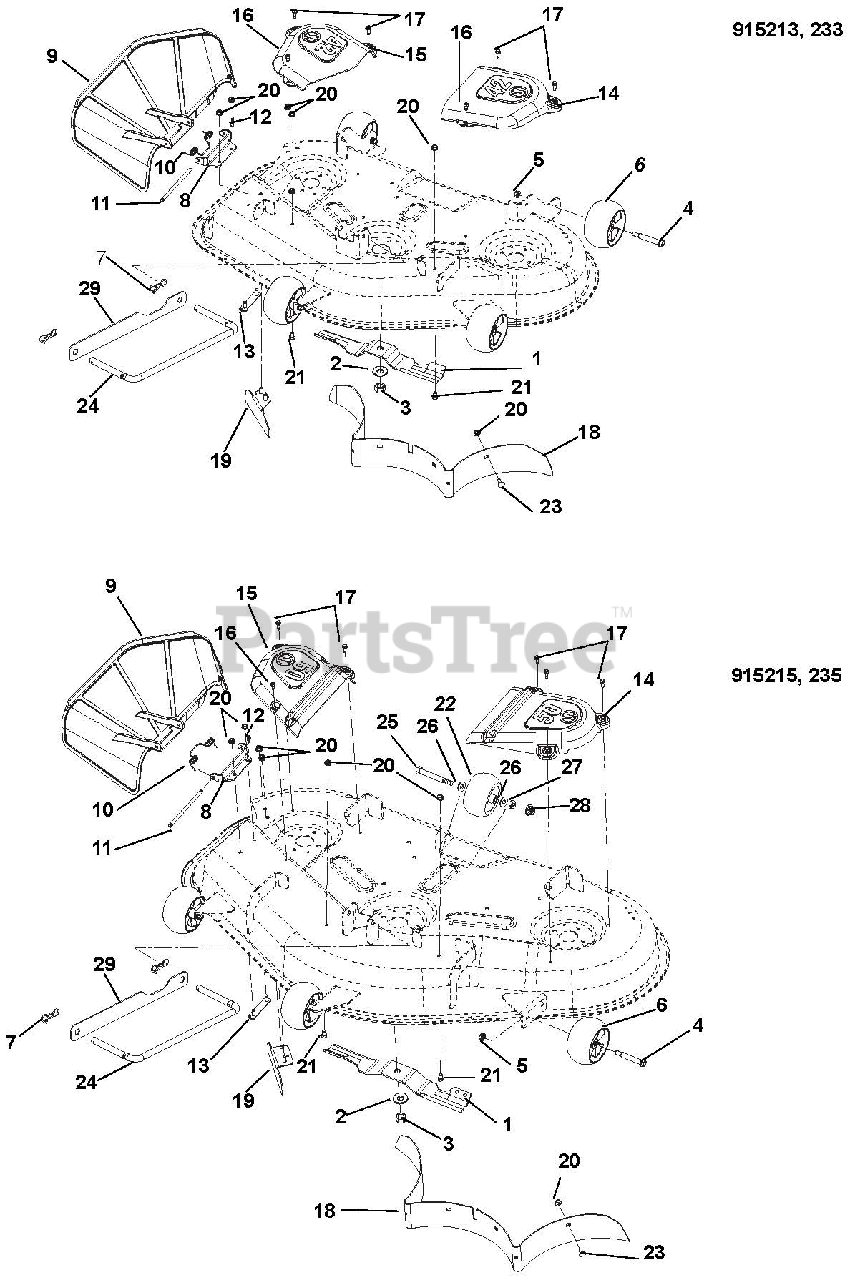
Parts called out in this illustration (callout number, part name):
1	BLADE, MOWER 14.83 (.188 THK)
1	BLADE, MOWER 17.35
2	WSHR-BLVL .669X1.535X.138
3	NUT-HEX .62-18 YWZC
4	BLT-SHLDR .38-16X2.50 HWH G5
5	@NUT-LK-TOP-FLG .38-16 YWZC
6	ANTI-SCALP WHEEL - 5X OS
7	PIN,BOW TIE LOCKING .091X1.875
8	BRKT-DISCHARGE CHUTE MOUNT 42"
8	BRKT, CHUTE MOUNT - 50"
9	CHUTE, DISCHARGE - MOLDED
10	SPRING-TORSION
11	PIN, 5/16 X 5.80"
12	PIN-HAIR INT .08X.18X1.18 YWZC
13	WMT-DISCHARGE CHUTE MT. STRAP
14	BELT COVER - LH 42"
14	BELT COVER - LH 50"
15	BELT COVER - RH 42"
15	BELT COVER - RH 50"
16	SCR-TAP .25-20X.50 HWH TR YWZ
17	SCR-TAP .25-20X.75 HWH TR YWZ
18	BAFFLE, REAR (42)
18	BAFFLE-50" STAMPED DECK REAR
19	WLDMT-BAFFLE, DISCHARGE 42"
19	BAFFLE, DEFLECTOR (50)
20	@NUT-LK-TOP-FLG .31-18 YWZC
21	@BLT-HEX .31-18X.50 GR5 YWZC
22	ROLLER
23	@BLT-RHDSSQNK .31-18X.75 G5YZ
24	WIREFORM, DRAG LINK
25	@BLT-HEX .38-16X3.50 GR5 YWZC
26	@WSHR-FL-STL.406X.812X.065 YWZ
27	@NUT-LK-CTR-JAM .375-16 YWZC
28	@NUT-LK-NYL-FLG .38-16 YWZC
29	STRAP, DRAG LINK
